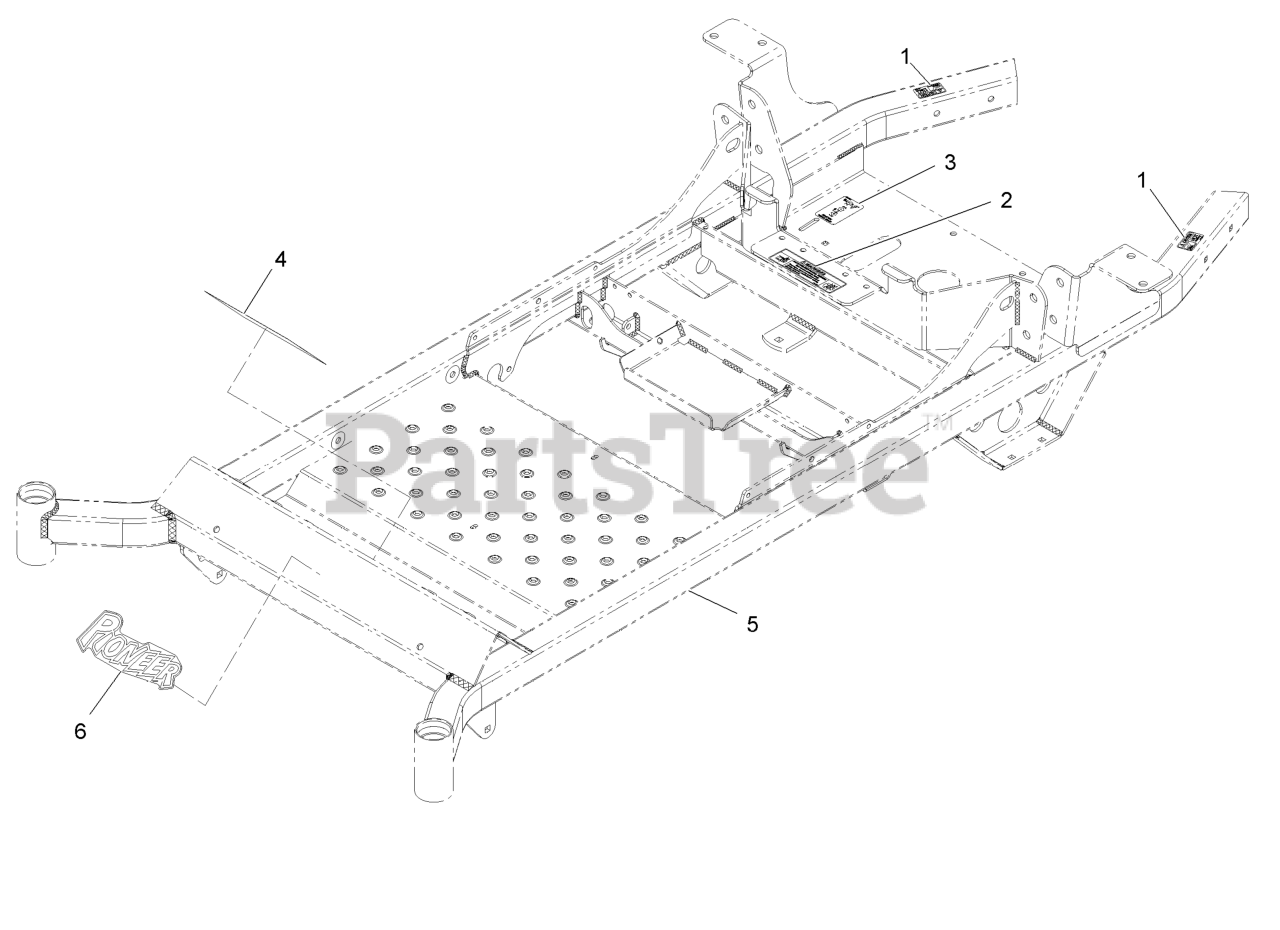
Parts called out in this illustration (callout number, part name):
1	DECAL-CAUTION
2	DECAL,BELT DRIVE
3	DECAL,DRIVE RELEASE
4	DECAL-SLOPE
6	DECAL-PIONEER LOGO
